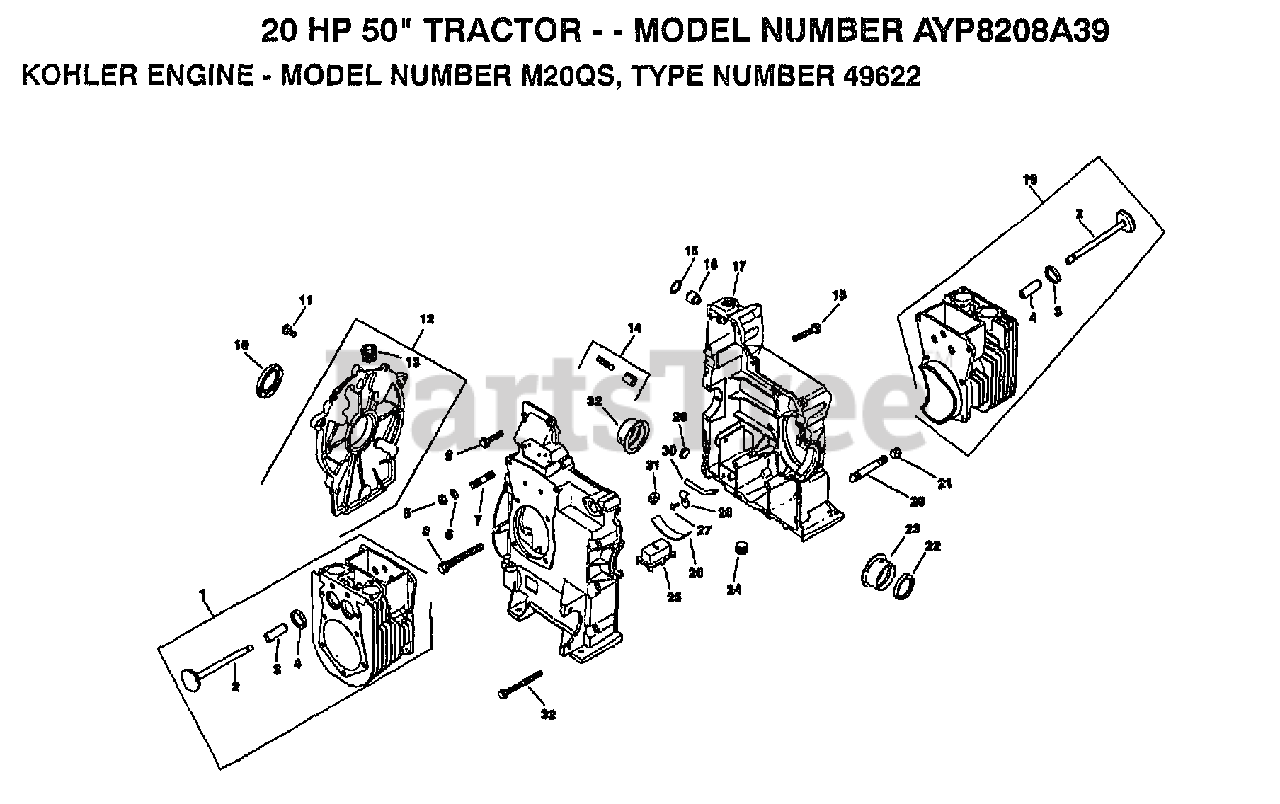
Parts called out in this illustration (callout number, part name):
1	KIT, #2 CYLINDER BARREL
2	VALVE, EXHAUST
3	GUIDE, VALVE
4	INSERT, VALVE SEAT
5	NUT
10	SEAL
11	SCREW
12	KIT, CLOSURE PLATE
13	PLUG
14	KIT, OIL RELIEF
15	RING, RETAINING
16	SHAFT, GOVERNOR
19	KIT, #1 CYLINDER BARREL
20	NIPPLE, PIPE
23	BEARING, SLEEVE
24	PLUG
25	HOUSING, OIL PICKUP
26	CLAMP, SPRING
27	SCREW
29	PLUG, CUP
30	TUBE, DIPSTICK
32	SEAL, OIL, FRONT
